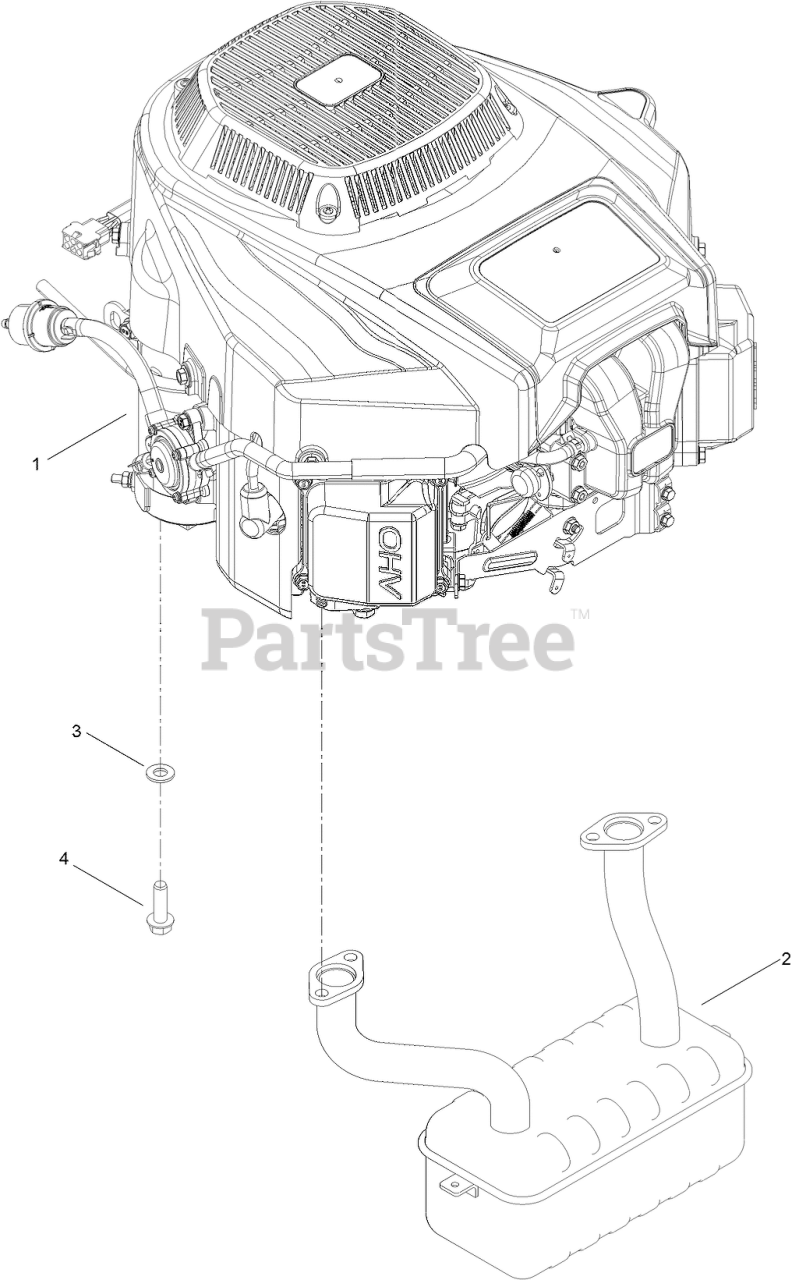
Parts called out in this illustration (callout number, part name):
1	ENGINE-2P77F
2	MUFFLER
3	WASHER-FLAT
4	SCREW-HWH, THD ROLL
